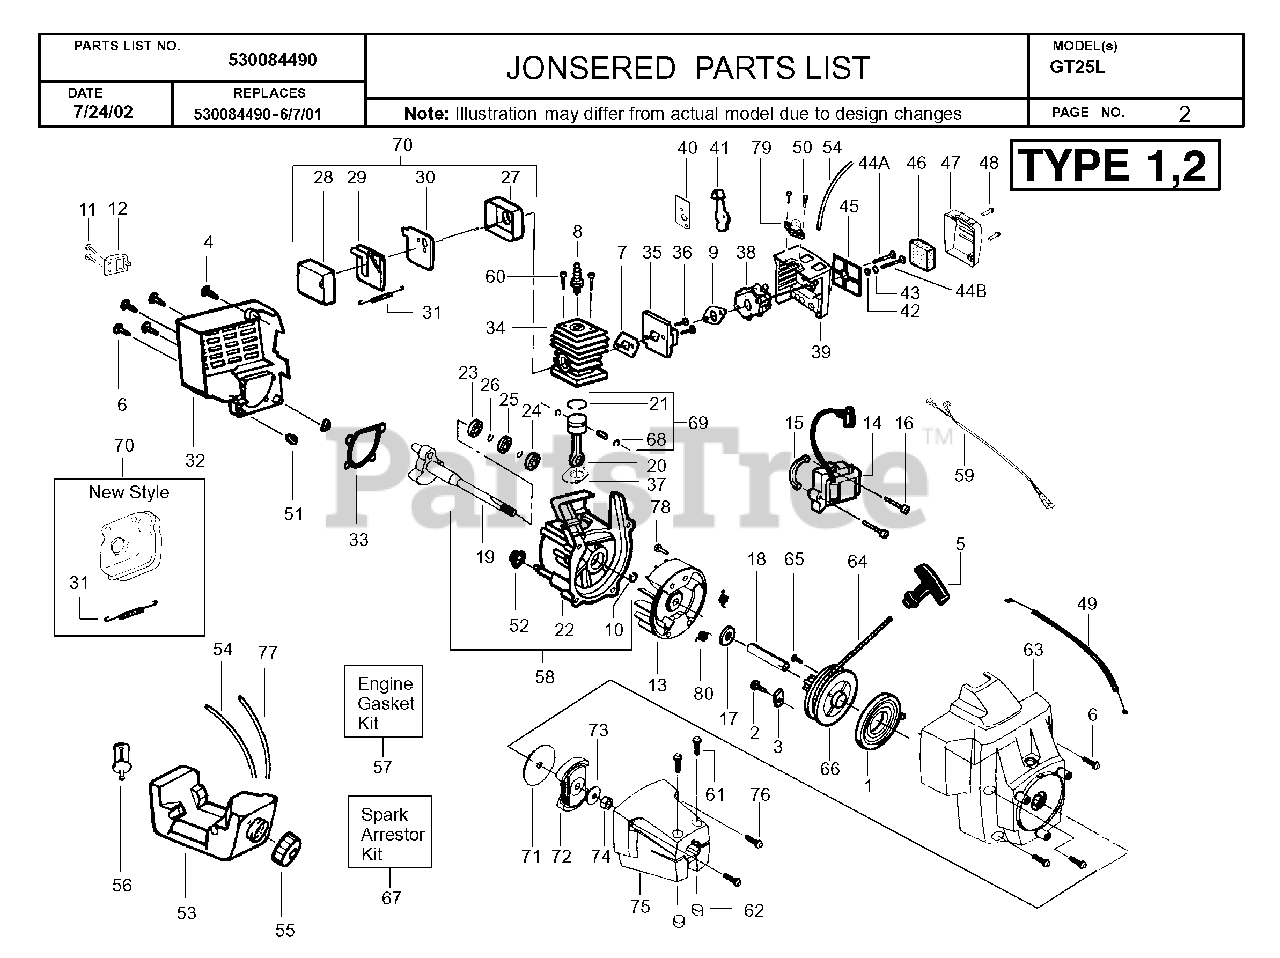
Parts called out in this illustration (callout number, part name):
1	STARTER SPRING
2	SCREW 8-16 X 9/16 (PLAS
5	HANDLE-STARTER
6	SCREW - SHROUD
7	GASKET - CYLINDER / CARB ADAPT
11	SCREW-8-18 X 5/18(RECES
12	MUFFLER GUARD
13	FLYWHEEL
14	IGNITION MODULE
15	SPACER - IGNITION MODULE
20	CONNECTING ROD ASSEMBLY
21	PISTON RING
22	CRANKCASE ASSY
23	BEARING
25	SEALING RING
26	RETAINING RING
27	MUFFLER BODY
28	MUFFLER COVER
33	GASKET, CRANKCASE
34	CYLINDER
36	SCREW - CARB. ADAPTOR
37	GASKET - CYLINDER
38	CARBURETOR
40	CHOKE PLATE
41	CHOKE SHUTTER
43	CHOKE SPACER
45	FILTER PLATE
46	AIR FILTER FOAM
47	AIR FILTER COVER
51	SHROUD ISOLATOR
53	TANK UNIT
54	KIT-LINE(FUEL)
55	CAP ASSY W/ RETAINER
56	FUEL PICK-UP ASSY
57	GASKET KIT
58	CRANKCASE/CRANKSHAFT ASSEMBLY
59	LEAD WIRE ASSEMBLY
61	SCREW - PINCH CLAMP
62	LOCKNUT-HEX 10-24
66	STARTER PULLEY KIT
68	WRIST PIN RET.
69	PISTON KIT
71	FRICTION DISC,CLUTCH 36/41
72	CLUTCH ASSEMBLY KIT
73	WASHER FLAT
75	CLUTH COVER
76	SCREW-10-14 X 13/16 (PL
77	FUEL LINE - PRIM/TNK
79	AIR PURGE BUBBLE
80	SPRING STR DOG
530069380	KIT-SPARK ARRESTOR (OLD STYLE)
530069989	MUFFLER (OLD STYLE)
530071390	MUFFLER KIT
